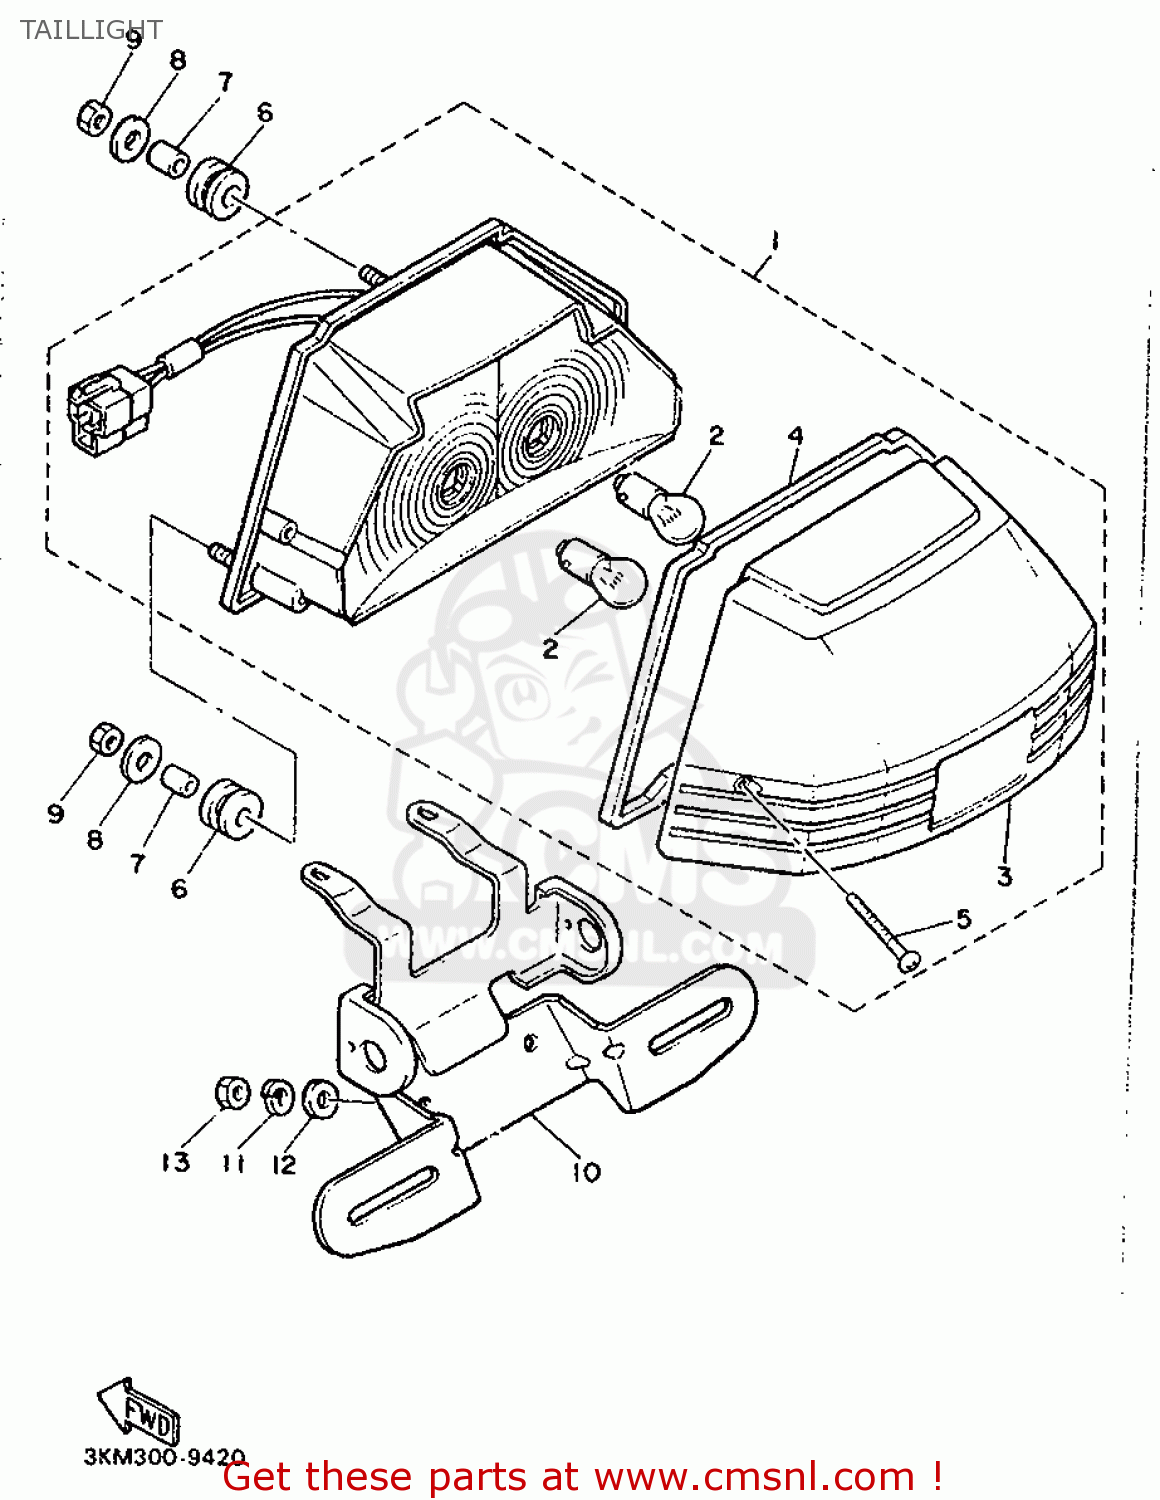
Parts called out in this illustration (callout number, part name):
01	TAILLIGHT UNIT ASSY
02	BULB
03	LENS, TAILLIGHT
04	GASKET, TAIL LENS
05	SCREW, TAPPING (25K)
06	DAMPER, TAIL 1
07	COLLAR
08	WASHER, PLATE(481)
09	NUT, HEXAGON(663)
10	BRACKET, LICENSE
11	WASHER,SPRING
12	WASHER, PLATE (838-77728-00)
13	NUT (31A)
